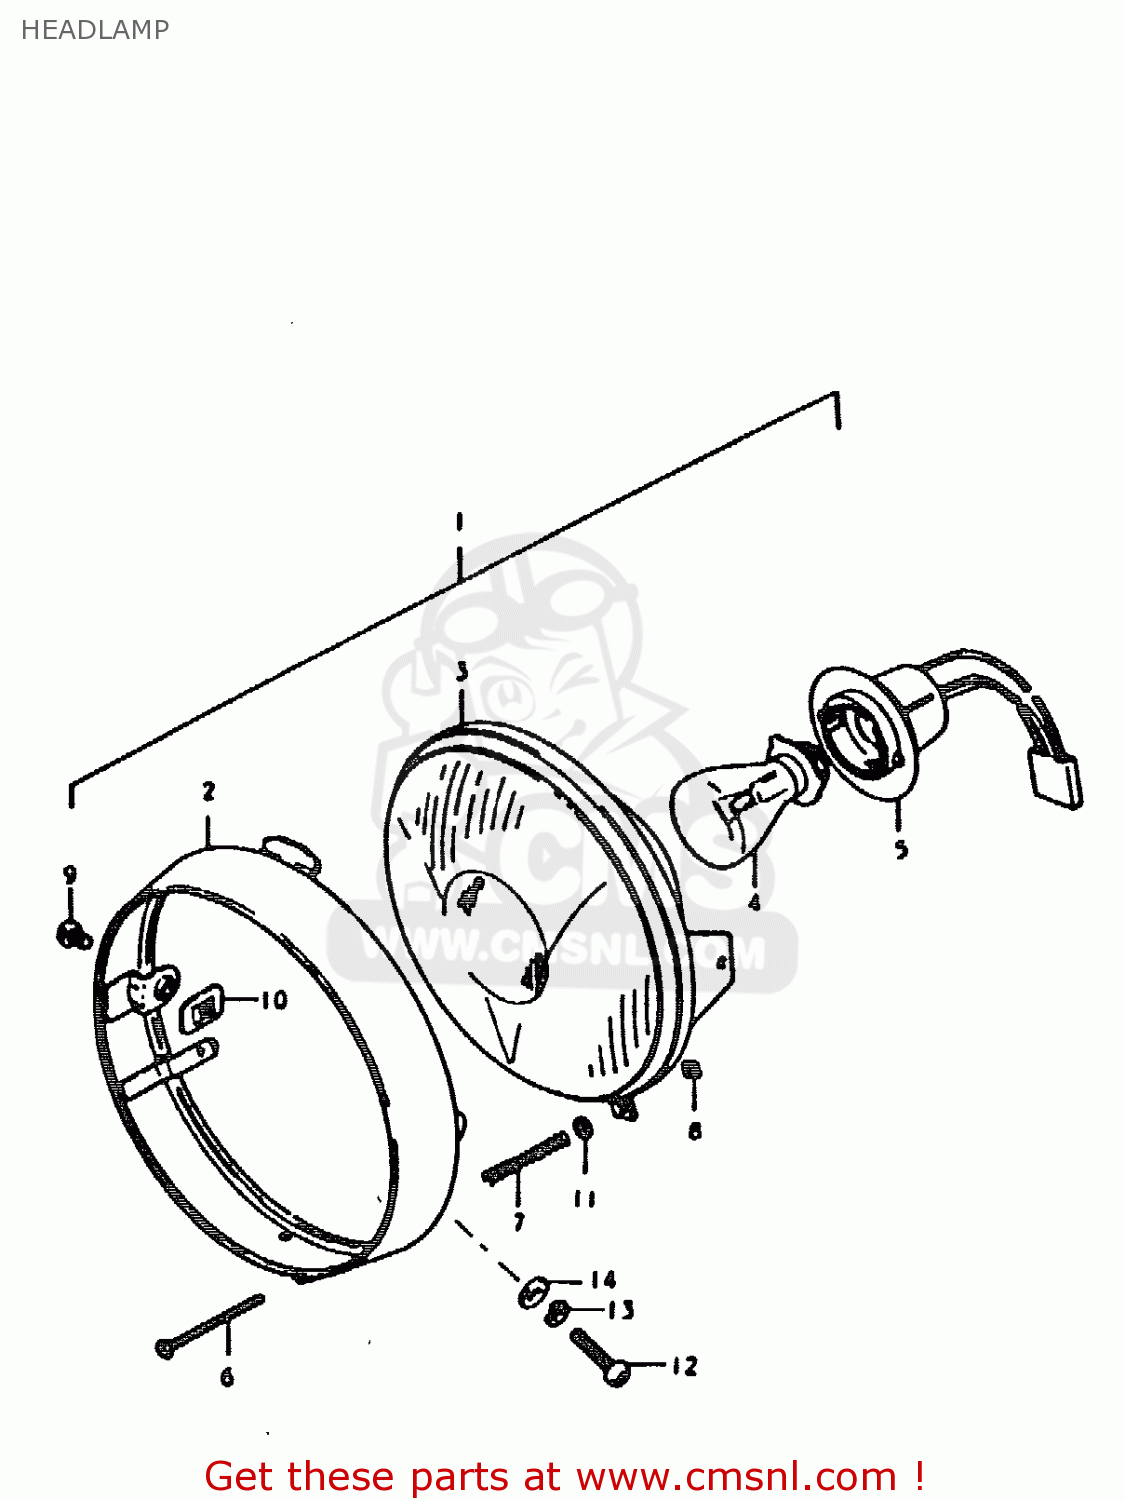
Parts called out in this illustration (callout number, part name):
1	HEADLAMP ASSY
2	RIM
3	LAMP UNIT
4	BULB(6V25/25W,STANLEY,A7007)
5	SOCKET,HEADLAMP
6	SCREW,HEADLAMP ADJUST
7	SPRING
8	NUT,HEADLAMP ADJUSTER
9	SCREW
10	NUT
11	WASHER
12	SCREW
13	LOCK WASHER
14	WASHER
